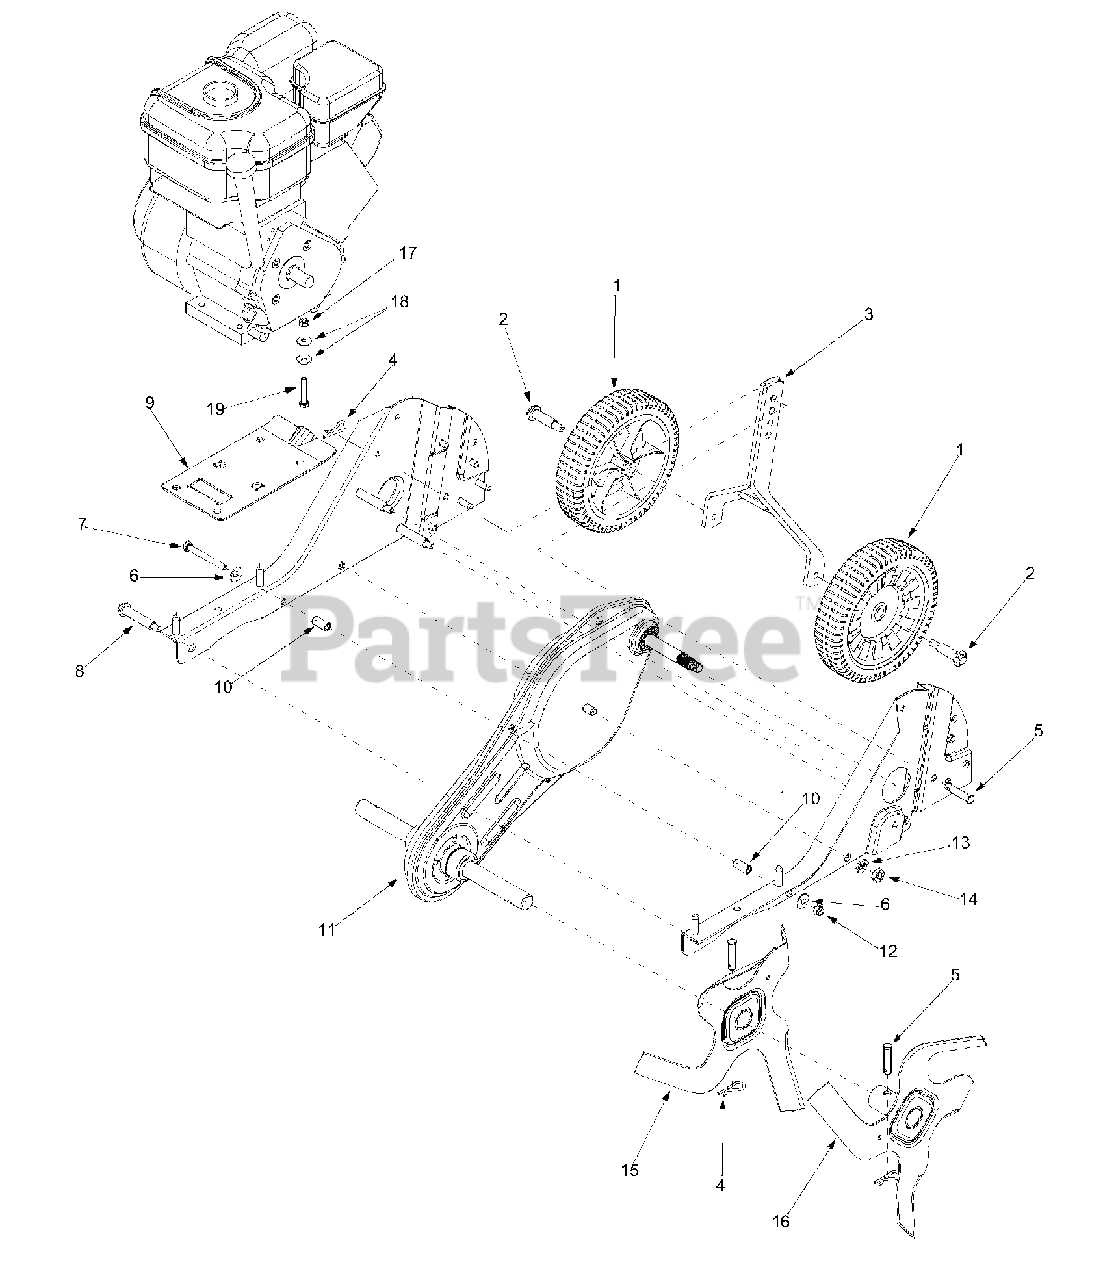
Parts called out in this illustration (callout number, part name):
1	Wheel 8 x 1.75
2	Shoulder Screw
4	Cotter Pin
5	Clevis Pin
6	Bell Washer .340 ID x .872 OD
7	Hex Cap Screw 5/16-18 x 3.0
8	Shoulder Screw
10	Spacer .47 OD x .96Lg
11	Chain Case Assembly
12	Hex Lock Nut 5/16-18
13	Lock Washer 7/16
14	Jam Nut 7/16-20
17	Hex Nut 5/16-18
18	Bell Washer .340 ID x .872 OD
19	Hex Cap Screw 5/16-18 x 1.75
